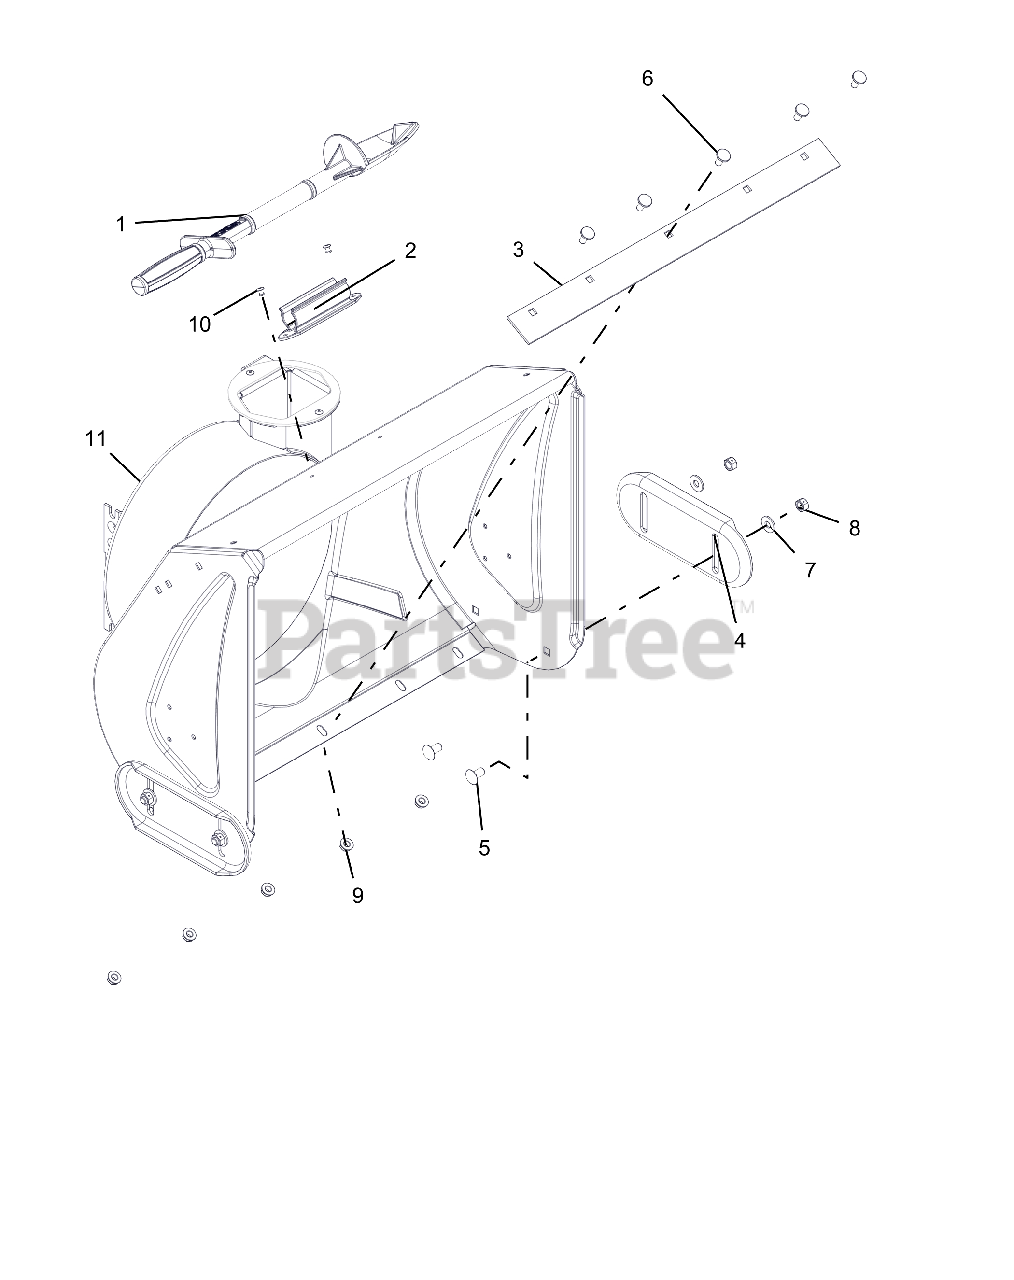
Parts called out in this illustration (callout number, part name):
1	DEVICE, SNOW CLEAN OUT
2	MOUNT, SNOW CLEAN OUT
3	SCRAPER BLADE, 22" COMPACT HI
4	SKID SHOE, REVERSIBLE
5	@BLT-RHDSSQNK .38-16X.75 G5YZ
6	BOLT, MODIFIED HEAD CARRIAGE
7	@WSHR-FL-STL.38X.875X.083 YWZC
8	@NUT-LK-CTR .38-16 YWZC
9	@NUT-LK-TOP-FLG .31-18 YWZC
10	RVT-POP .187 YZ
11	BLOWER HOUSING, 22"
